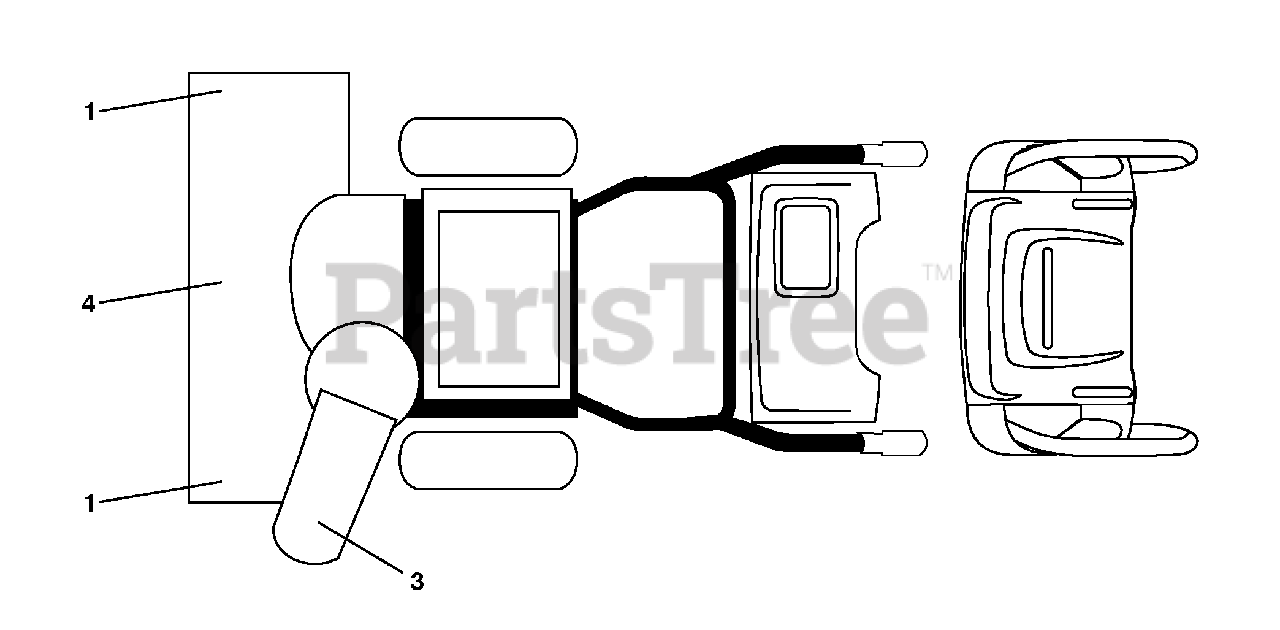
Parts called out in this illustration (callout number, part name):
1	DECAL, DANGER
3	DECAL, DANGER, DEFLECTOR
4	DECAL, DANGER
